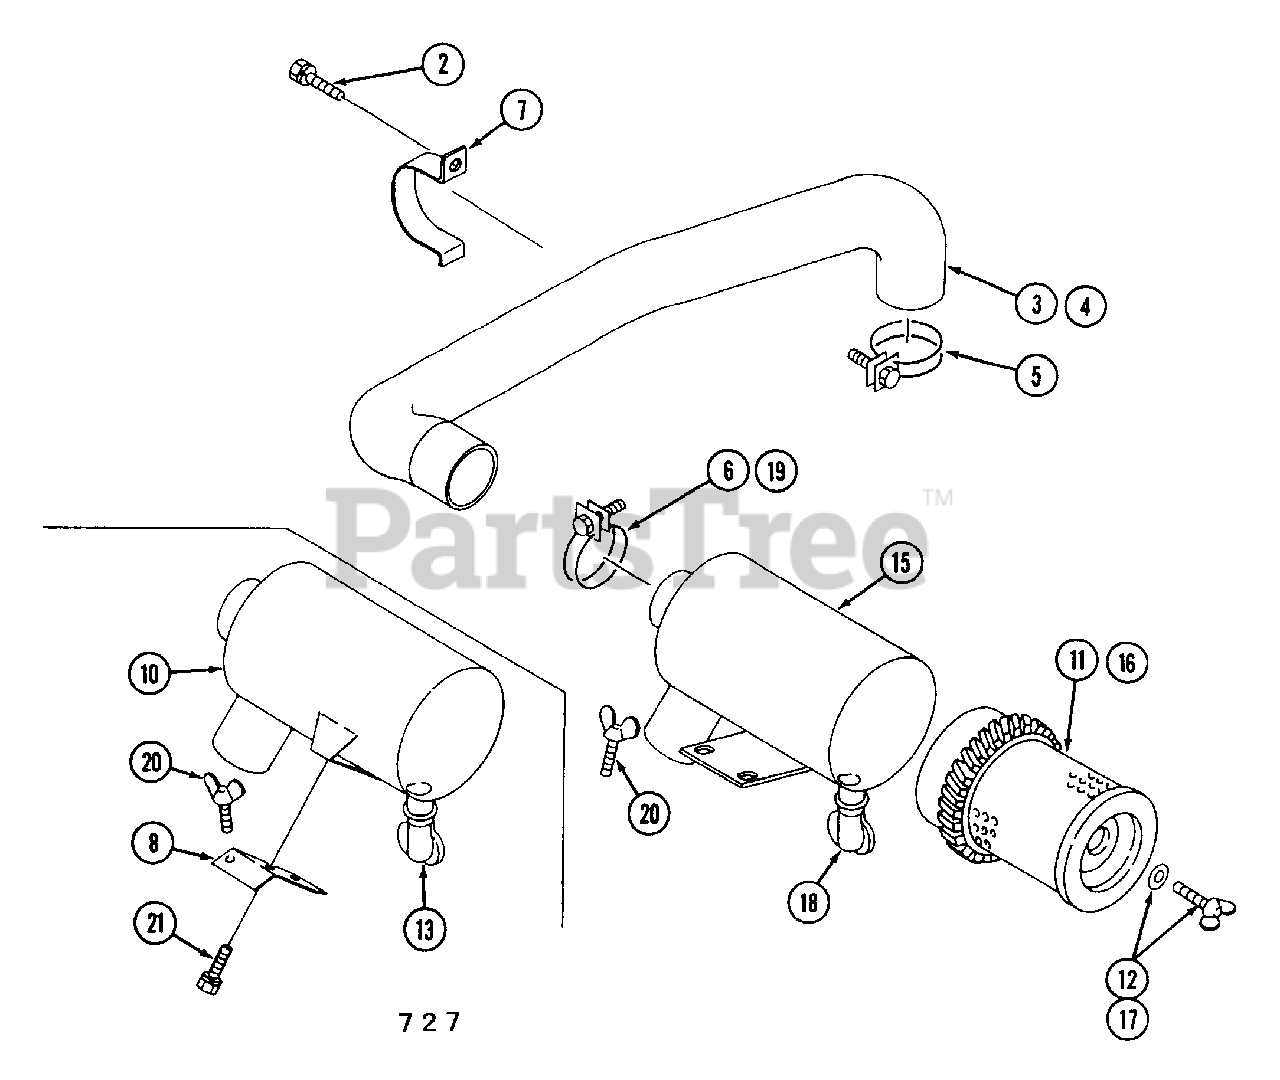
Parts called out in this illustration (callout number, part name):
4	Hose, Air
6	Band, Hose
8	Plate
10	Case Ass'y.
11	Element
12	Bolt, Ass'y., Wing
13	Valve
17	Bolt Ass'y., Wing
21	Bolt
